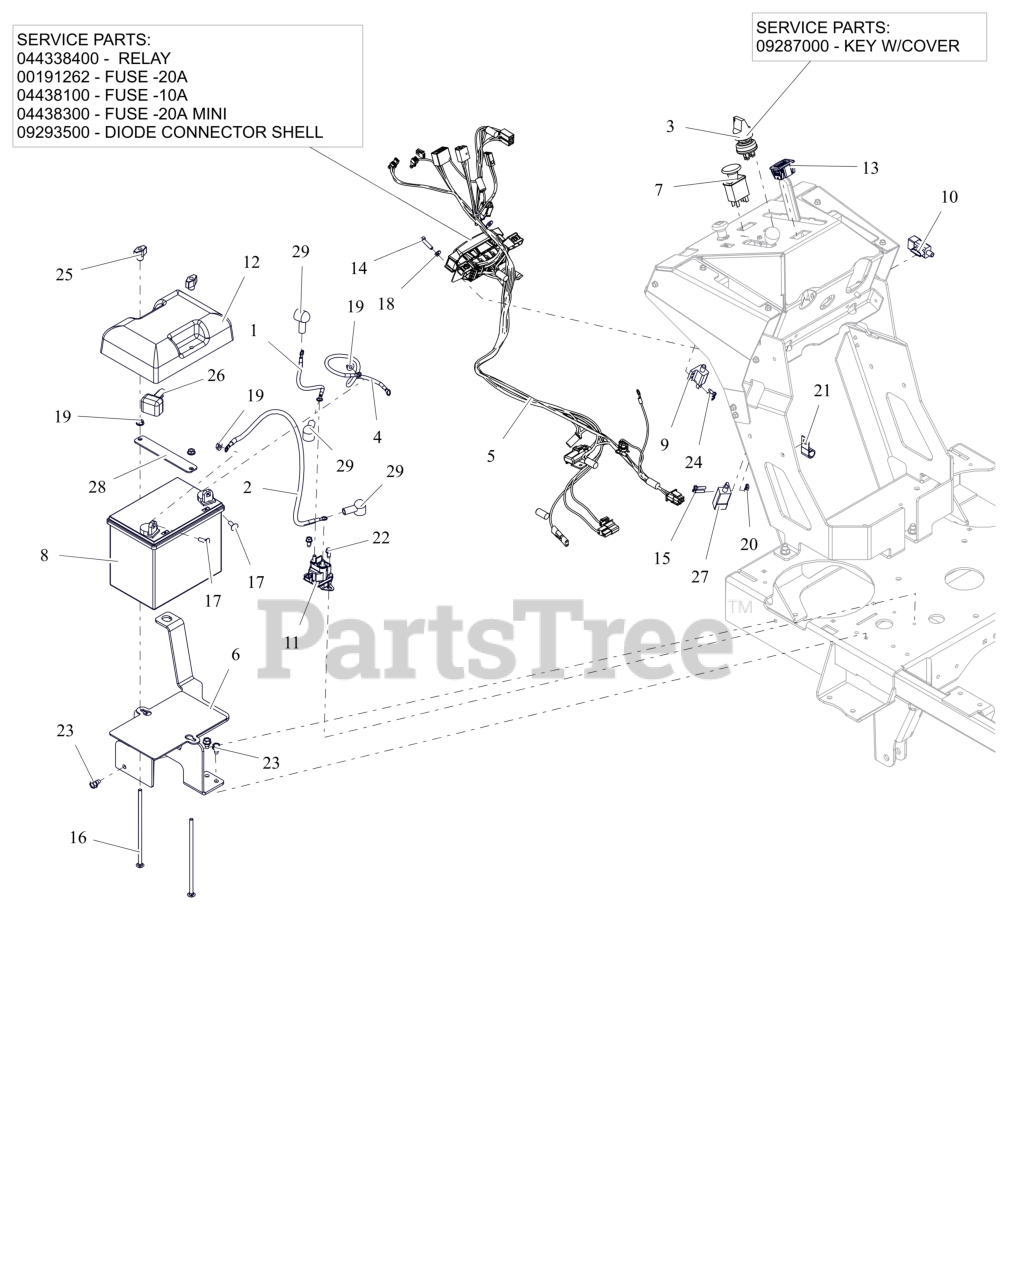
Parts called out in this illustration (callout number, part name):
1	CABLE-POSITIVE BATTERY 9.00"
2	CABLE - START 22.00"
3	SWITCH, IGNITION
3	KEY, W/ SHIELD
4	CBL,NEGATIVE BATTERY 20.00
5	HARNESS, 36-60 PRO-WALK
5	RELAY,MICRO5 TERML W/RESISTOR
5	FUSE, 20 AMP BLADE S/O
5	FUSE,10 AMP MINI-ATC
5	FUSE,20 AMP MINI ATC
5	DIODE, CONNECTOR SHELL
6	WLDMT, BATTERY TRAY 48"-60"
7	SWITCH, CLUTCH
8	BATTERY, 300 CCA 10U1L
9	SWITCH- SINGLE POLE N.O.
10	SWITCH, SNAP IN - N.O./N.O.
11	SOLENOID, STARTER (SEALED)
12	COVER, BATTERY
13	HOUR METER
14	BLT, HEX M6-1.0 X 25 G8.8 ZCC
15	BLT, HWH #10-24X.75 ZCC
16	BLT,RHSN .25-20X7.00 G2 ZCC
17	BLT, RHSN .25-20X.750 G5 ZCC
18	WSHR,FLT .281X.625X.065 ZCC
19	NUT-SPNLK-FLG .25-20 ZC120
20	NUT, HEX .250-20 GR5 ZCC
22	SCR-TAP .25-20X.50 HWH ZCC
23	SCR,TAP .312-18X.50 HWH TR ZCC
24	SCR,TAP #10-24X.50 HWH TR ZCC
25	KNOB, WING - .25-20 UNC
26	INSULATOR
27	SWITCH,INTERLOCK
28	STRAP, BATTERY
29	BOOT, EYELET TERMINAL
